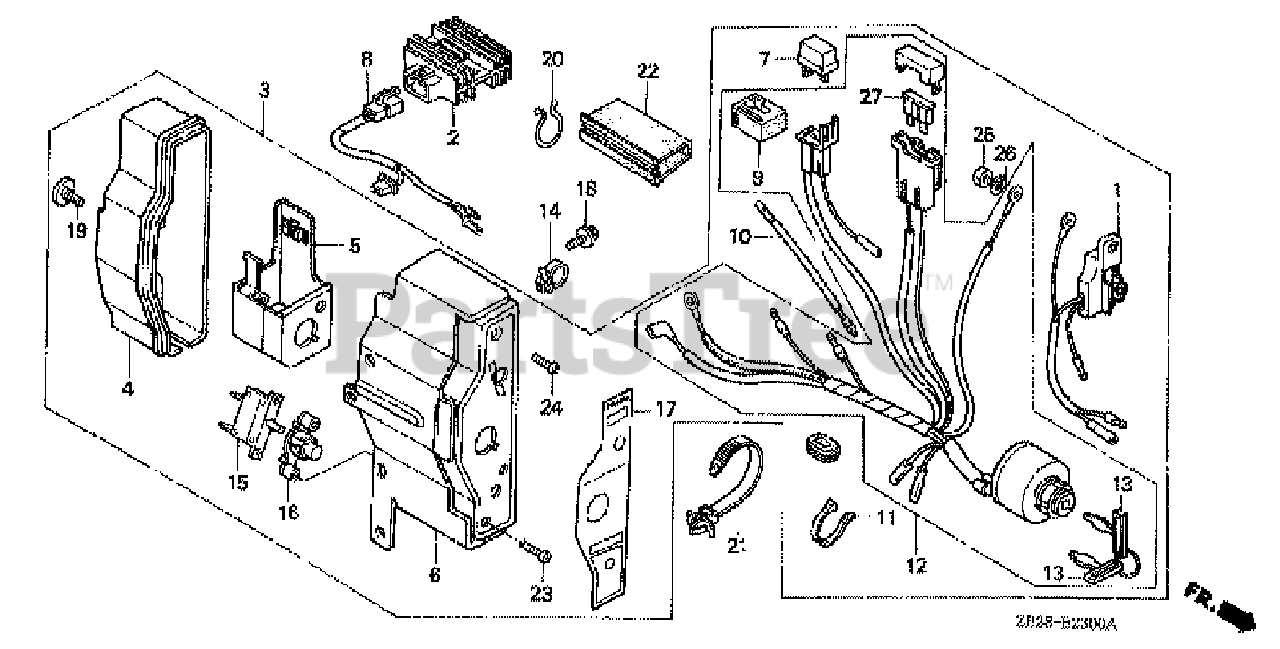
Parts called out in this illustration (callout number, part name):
2	RECTIFIER ASSY., REGULATOR
3	BOX ASSY., CONTROL *R8* (BRIGHT RED)
4	CASE, CONTROL
5	BRACKET, CASE MOUNTING
6	PANEL, CONTROL *R8**R8* (BRIGHT RED)
8	SUB-WIRE HARNESS ASSY.
10	SUB-HARNESS
11	BAND
12	SWITCH ASSY., COMBINATION
13	KEY
14	HOLDER, STOP SWITCH WIRE
17	MARK, CONTROL BOX (EXTERNAL-REGULATOR)
18	BOLT, FLANGE (6X12) (CT200)
19	SCREW, SPECIAL (6X12)
20	CLIP, PURSE LOCK
21	STRAP, CABLE (118MM) *NH1L* (BLACK)
22	TUBE, FASTENER (30)
24	SCREW, PAN (4X12)
25	NUT, HEX. (4MM) (NOT AVAILABLE)
26	WASHER, SPRING (4MM)
27	FUSE, BLADE (15A)
